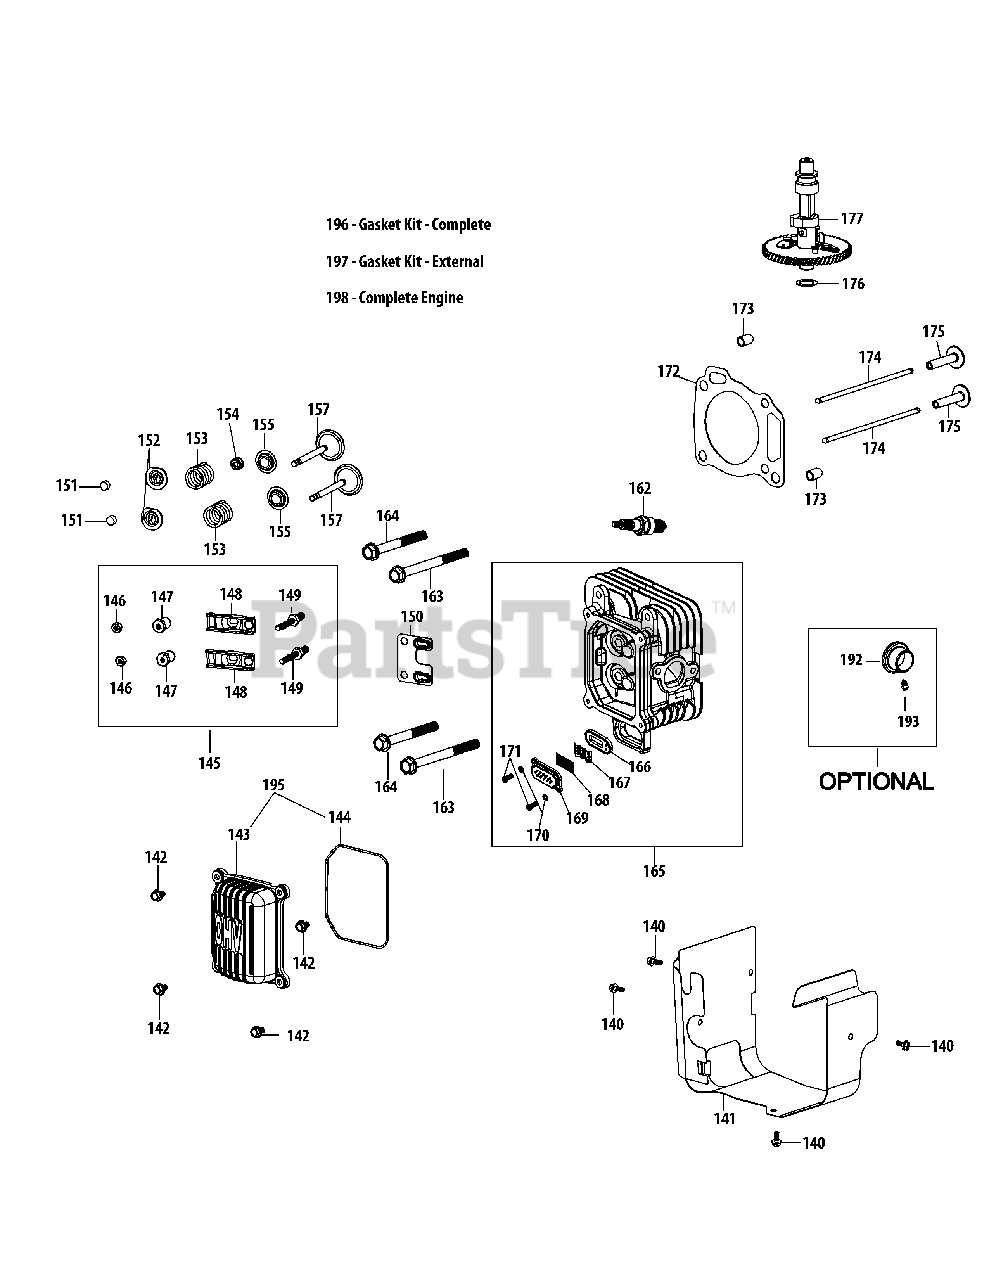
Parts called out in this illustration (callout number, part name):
140	Bolt M5×10
142	Valve Cover Bolt
143	Valve Cover
144	Valve Cover Ring
145	Rocker Arm Assembly
147	Fulcrum Nut
148	Rocker Arm
149	Rocker Arm Stud
150	Push Rod Guide
151	Exhaust Valve Adjuster
152	Exhaust Valve Spring Retainer
153	Valve Spring
154	Intake Valve Seal
155	Valve Spring Retainer
162	Spark Plug
163	Bolt M10×1.25×85
164	Bolt /M10×1.25×65
165	Cylinder Head Asm
165	Cylinder Head Kit
166	Air Valve Core
167	Strainer Clip
168	Strainer
169	The Air Valve Bonnet
171	Screw M5×12
172	Cylinder Head Gasket
173	Cylinder Head Dowel 12×16
174	Push Rod Kit
175	Tappet
176	Camshaft Thrust Washer
177	Camshaft Assembly
192	Spark Arrestor
193	Spark Arrestor Screw
195	Valve Cover Kit
196	Gasket Kit - Complete
197	Gasket Kit - External
198	Complete Engine
